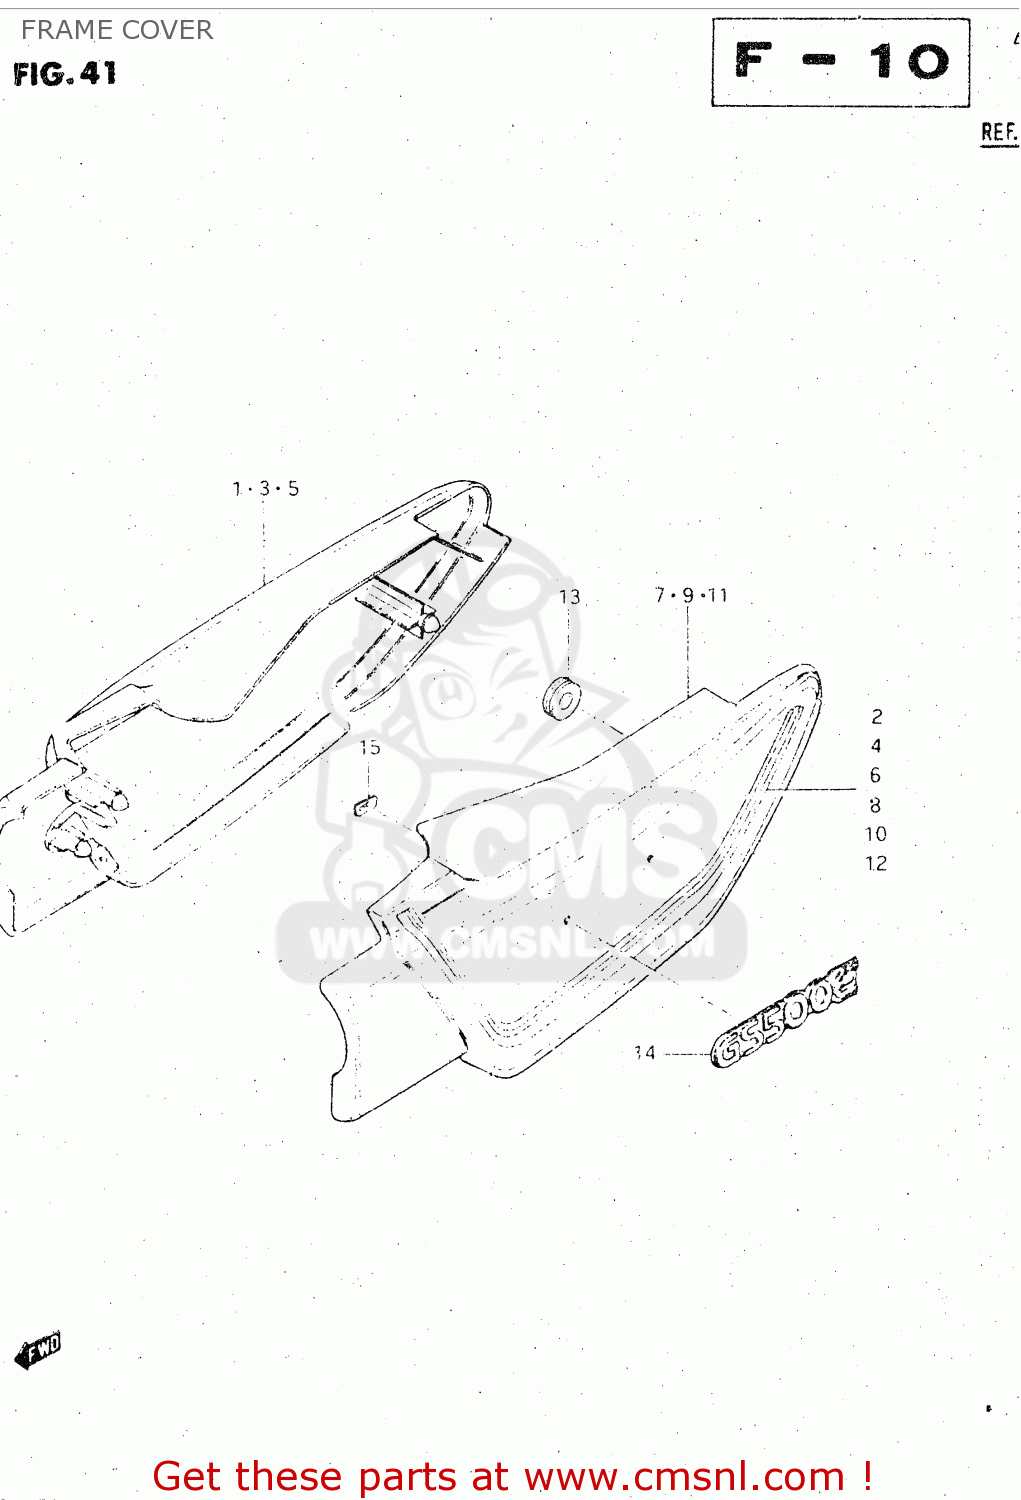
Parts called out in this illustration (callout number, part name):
1	COVER,FRAME,RIGHT
2	TAPE, RH
3	COVER, FRAME RH (RED)
4	TAPE, RH
5	COVER, FRAME RH (BLUE)
6	TAPE, RH
7	COVER,FRAME,LEFT
8	TAPE, LH
9	COVER, FRAME LH (RED)
10	TAPE, LH
11	COVER, FRAME LH (BLUE)
12	TAPE, LH
13	CUSHION
14	EMBLEM
15	NUT
